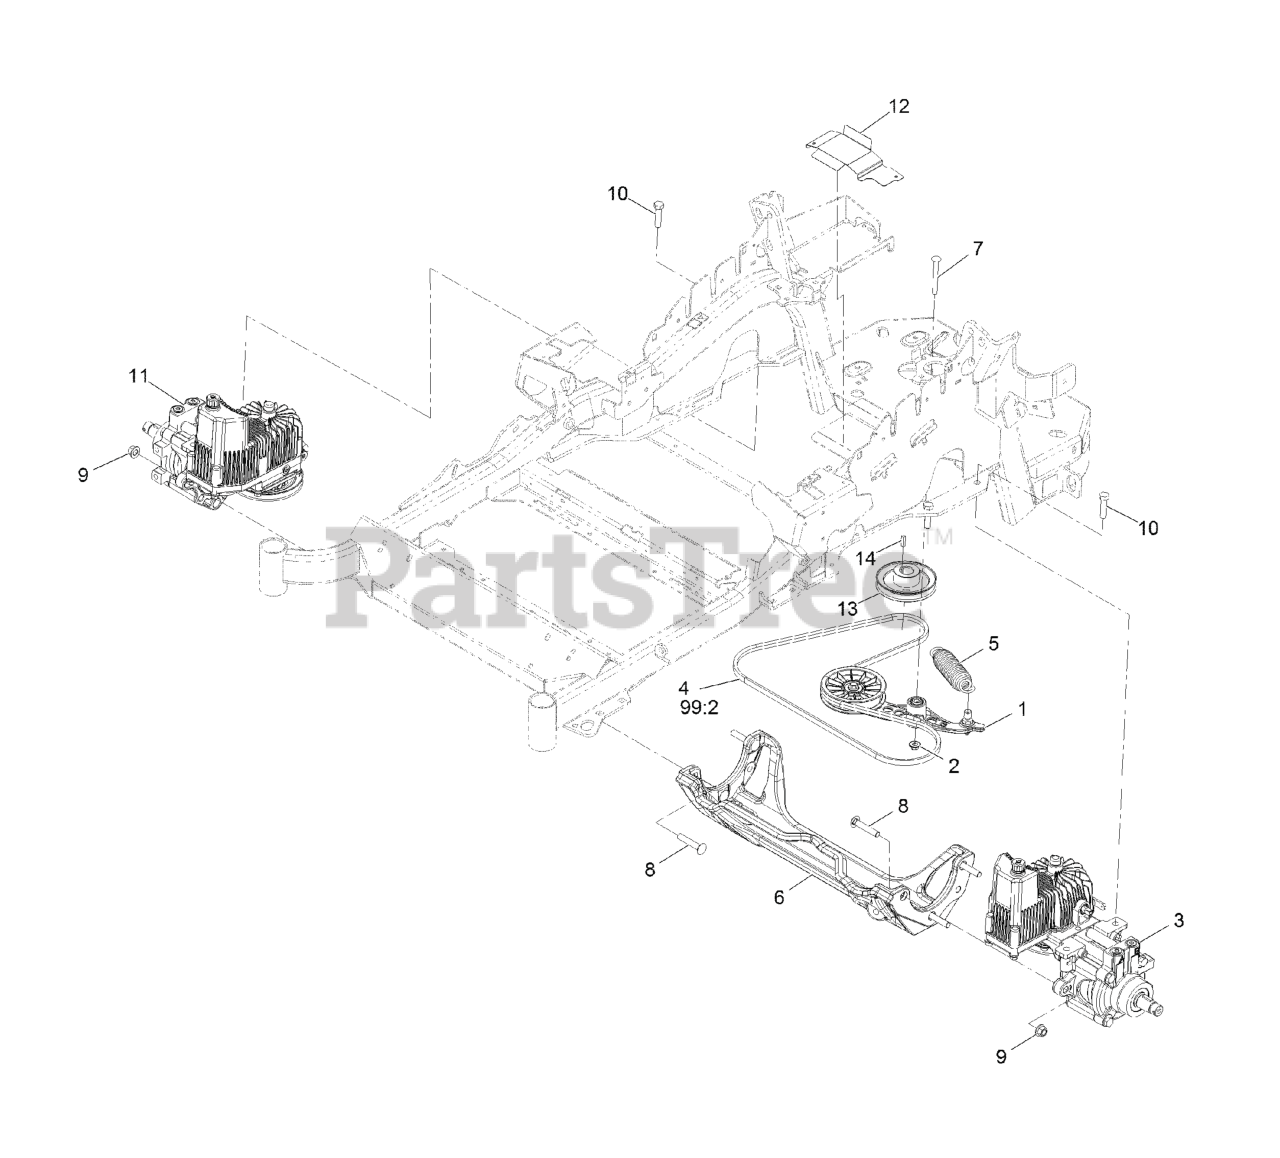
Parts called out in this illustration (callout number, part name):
1	PUMP IDLER ASM
2	Nut-Nyloc 3/8-16 Flg
3	LH HYDRO ASM (12CC NO FAN
5	SPRING-EXTENSION
6	CRADLE-HYDRO
7	BOLT-SHOULDER, CARRIAGE 3/8-16 X 3 1/2
8	SCREW-CARR
9	Nut-Lock 1/2-13
10	SCREW-HH
11	RH HYDRO ASM (12CC NO FAN
12	GUARD-BELT
13	SHEAVE-PUMP, DRIVE
99:2	BELT-V
